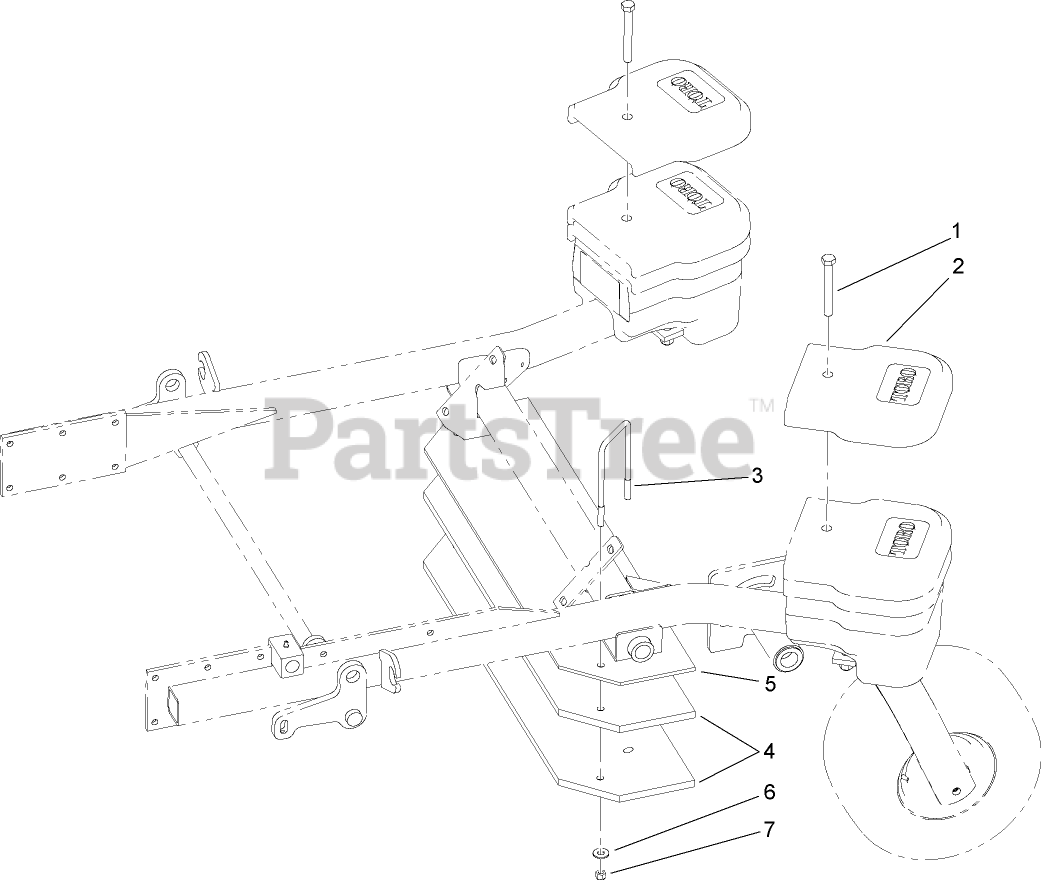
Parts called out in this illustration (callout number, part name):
1	SCREW-HH
2	WEIGHT-TOP
3	U-BOLT
4	BAR-WEIGHT
5	BAR-WEIGHT
6	WASHER-FLAT
7	NUT-LOCK, NI
